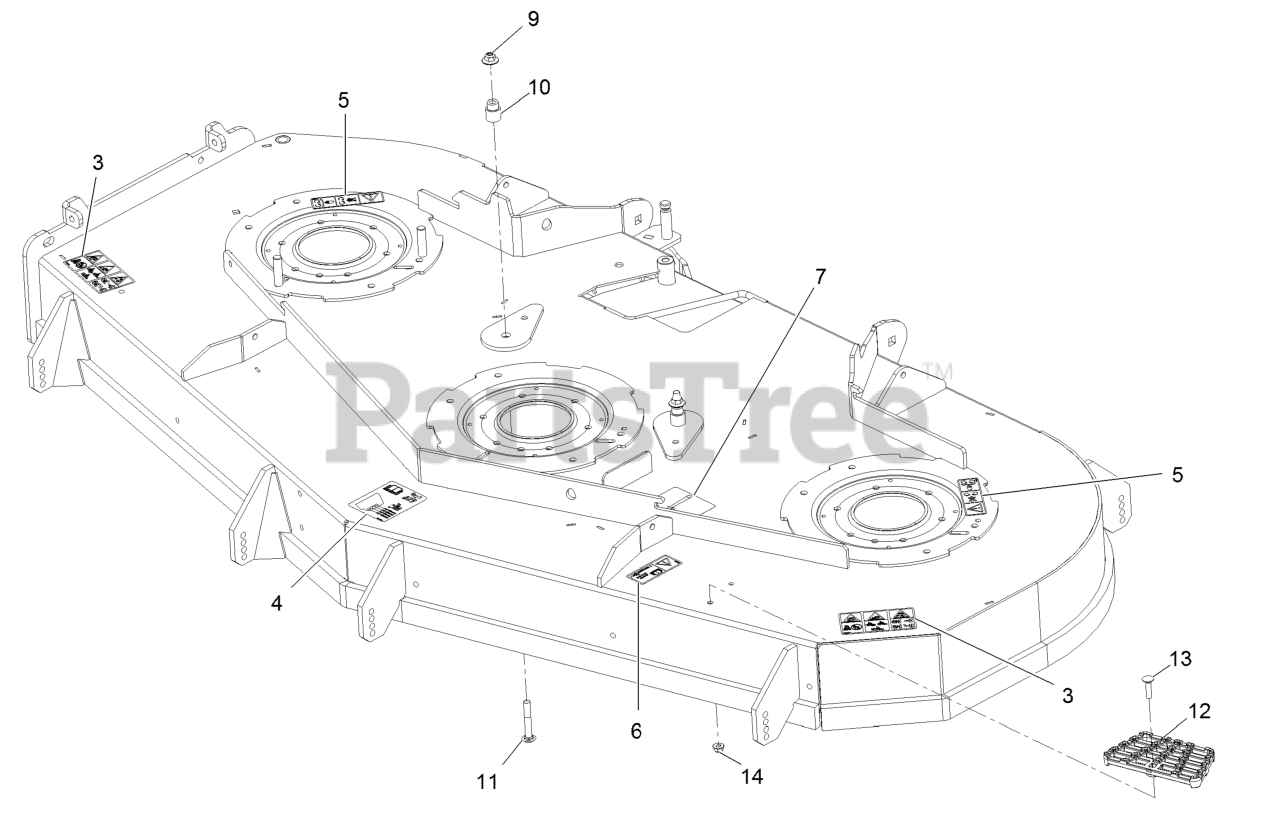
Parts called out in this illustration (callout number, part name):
3	Decal-Danger Thrown Objects
4	Decal-Roller, Anti-Scalp
5	Decal-Cover, Missing
6	Decal-Bolt Torque
7	Decal-Belt Routing
9	Nut-Flange, NI
10	Bushing, Idler
11	Screw-CARR
12	Step-Deck
13	Screw-CARR
14	Nut-HF, NI
